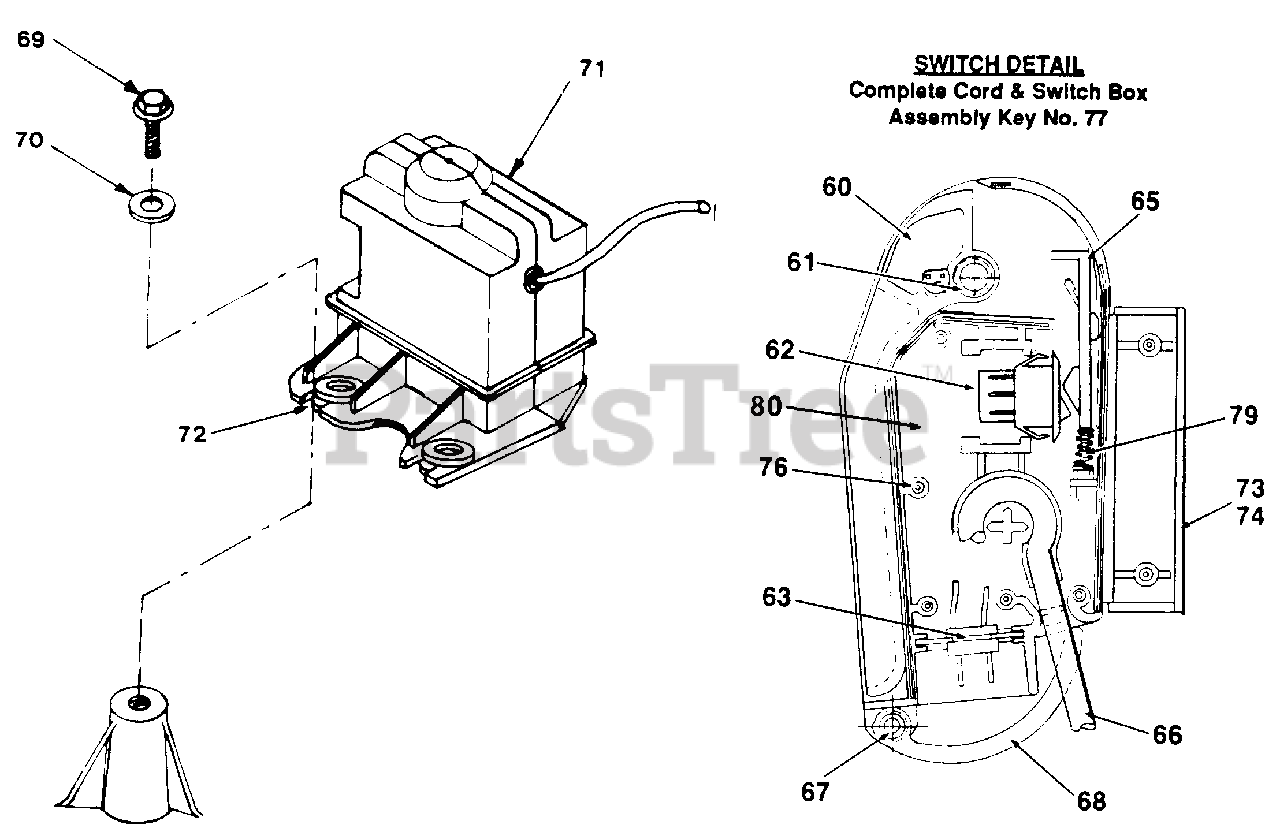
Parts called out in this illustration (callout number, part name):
60	Handle-Switch
61	Spring
62	Switch
63	Plug Assembly
65	Latch
66	Cord Assy.
67	Spring - Plug Ret.
68	Plug Retainer
69	Bolt, Motor Mount
70	Washer-1/4" ID x 3/4" OD x 1/16" Thick
71	Motor & Switch Assy. (Complete)
72	Insulator, Motor Housing
73	Housing - Upper Half
79	Latch Spring
